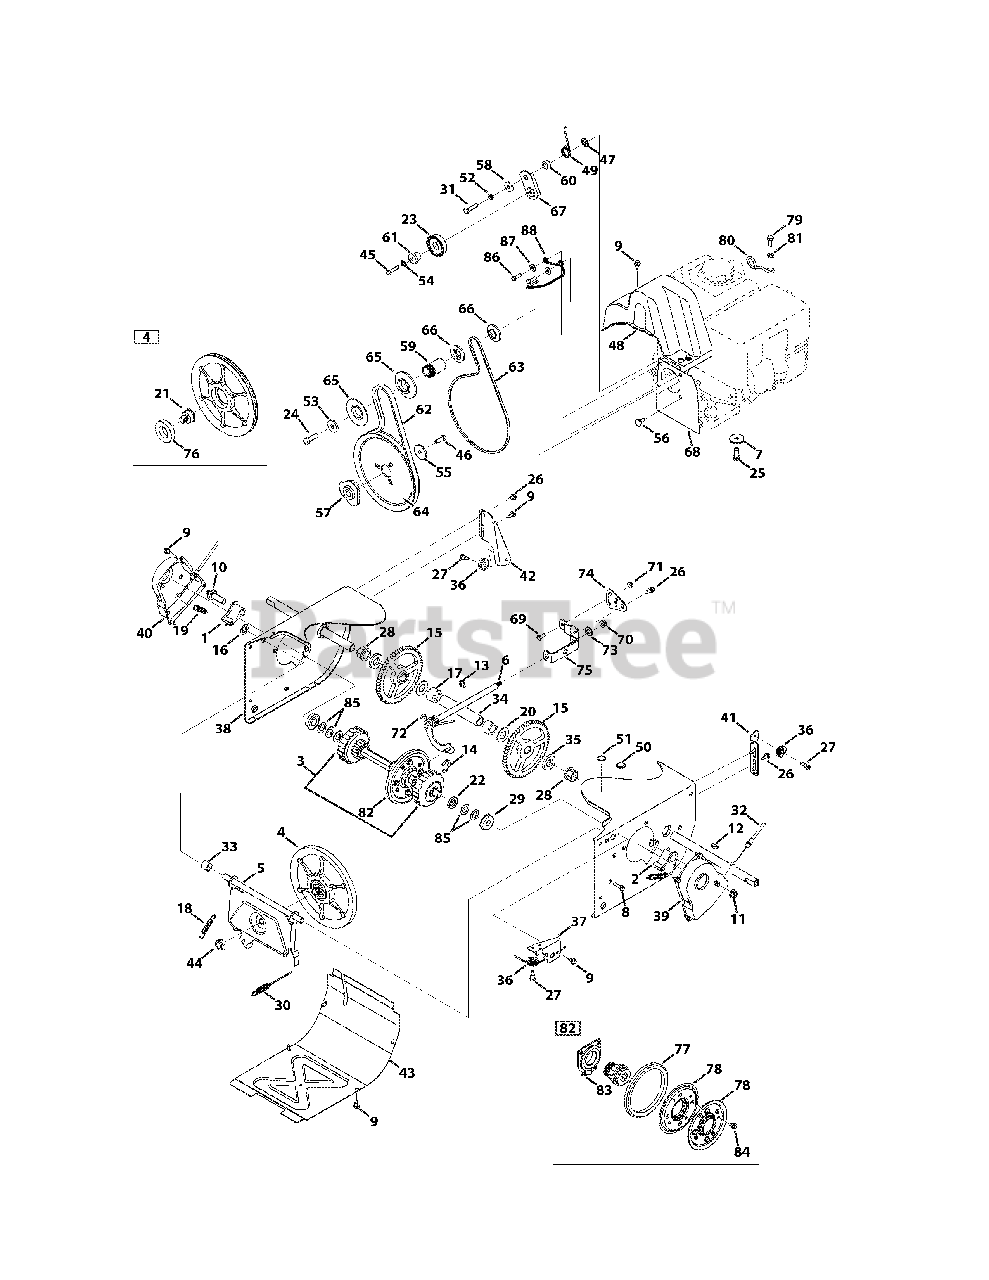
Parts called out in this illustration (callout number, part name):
1	Dogg Assembly, RH
2	Dogg Assembly, LH
3	Drive Shaft Assembly
4	Friction Wheel Disc Assembly
5	Friction Wheel Support
6	Rod Shift Assembly
7	Washer, Flat, .38 x 1.38
8	Screw, 1/4-20 x 1.000
9	Screw, 1/4-20 x .625
10	Actuator Shaft
11	Nut, Flangelock, 3/8-16
12	Hi-Pro Key, 3/16 x 3/4 DIA
14	Retainer Ring
16	Nut, Speed, .500
17	Spacer, .76 x .75
18	Extension Spring, .380 x 2.500
19	Extension Spring, .500 x 1.71
20	Washer, Flat, .76 x 1.49
21	Friction Pin, Disc Bearing
22	Spacer, .68 ID x 1.25 OD x .20
23	Pulley Assembly
24	Hex Head Screw, 3/8-24 x 1.25
25	Taptite Sems Screw, 3/8-16 x 1.000
26	Screw, Shoulder, .368 x .113 x 1/4-20
27	C Screw, Shoulder, .340 x .335 x 1/4-28
28	Hex Flange Bearing, .75 ID
29	Ball Bearing, 17 x 40 x 12
30	Drive Clutch Cable
31	Hex Head Screw, 5/16-24 x 1.25
32	Steering Cable
33	Spacer, .508 x .75
34	Axle Support Tube
35	Spacer, Axle
36	Roller Cable
37	Auger Cable Guide Bracket
38	Wheel Drive Frame
39	Shaft Retainer, LH
40	Shaft Retainer, RH
41	Auger Clutch Cable Guide Bracket
42	Drive Clutch Cable Guide Bracket
44	Nut, Flange, 5/8-18
45	Taptite Screw, 1/4-20 x 1.250
46	Hex Head Screw, 5/16-24 x .875
47	Nut, Push-On, .25 DIA
48	Belt Cover, 4-Way lrg. block
49	Spring, Torsion, .850 x .333
50	Plug, 3/8 ID
51	Plug, 1/2 ID
52	Washer, Lock, 5/16
53	Washer, Flat, .45 x 1.5
54	Washer, Lock, 1/4
55	Washer, Flat, .34 x 1.50
56	Screw, Shoulder
57	Pulley Adapter, .75 DIA
58	Spacer, Shoulder, .3175 x .500
59	Spacer, .875 x 1.185
60	Spacer, .340 x .750
61	Spacer, Shoulder, .260 x .785
62	Auger Drive Belt, 4-Way lrg. block
63	V Belt, 3L x 36.64"
64	Auger Pulley, 8.1 x .5
65	Pulley, Half, 4L-V x 2.600
66	Pulley, Half, 3/8-V x 2.2
67	Drive Idler Bracket
68	Cover Plate, 4-Way lrg. block
69	Hex Head Screw, 1/4-20 x .620
70	Nut, Flangelock, 5/16-18
71	Nut, Flangelock, 1/4-20
72	Spring, Torsion, .750 x .968
73	Washer, Flat, .469 x .875 x .105
74	Speed Selector Pivot Bracket
75	Speed Selector Shift Bracket
76	Ball Bearing, 30 x 55 x 13
77	Friction Wheel, 5.5 OD
78	Friction Wheel Plate
79	Hex Head Screw, 1.25 x 20
80	Cable Guide
81	Washer, Flat, .330 x .630
82	Friction Wheel Assembly
83	Bearing Assembly, Friction Wheel
84	Screw, 5/16-18 x .750
85	Flat Washer, .67 x 1.174 x .02
86	Hex Head Screw, 5/16-24 x 1.00
87	Washer, Flat, .349 x .879
